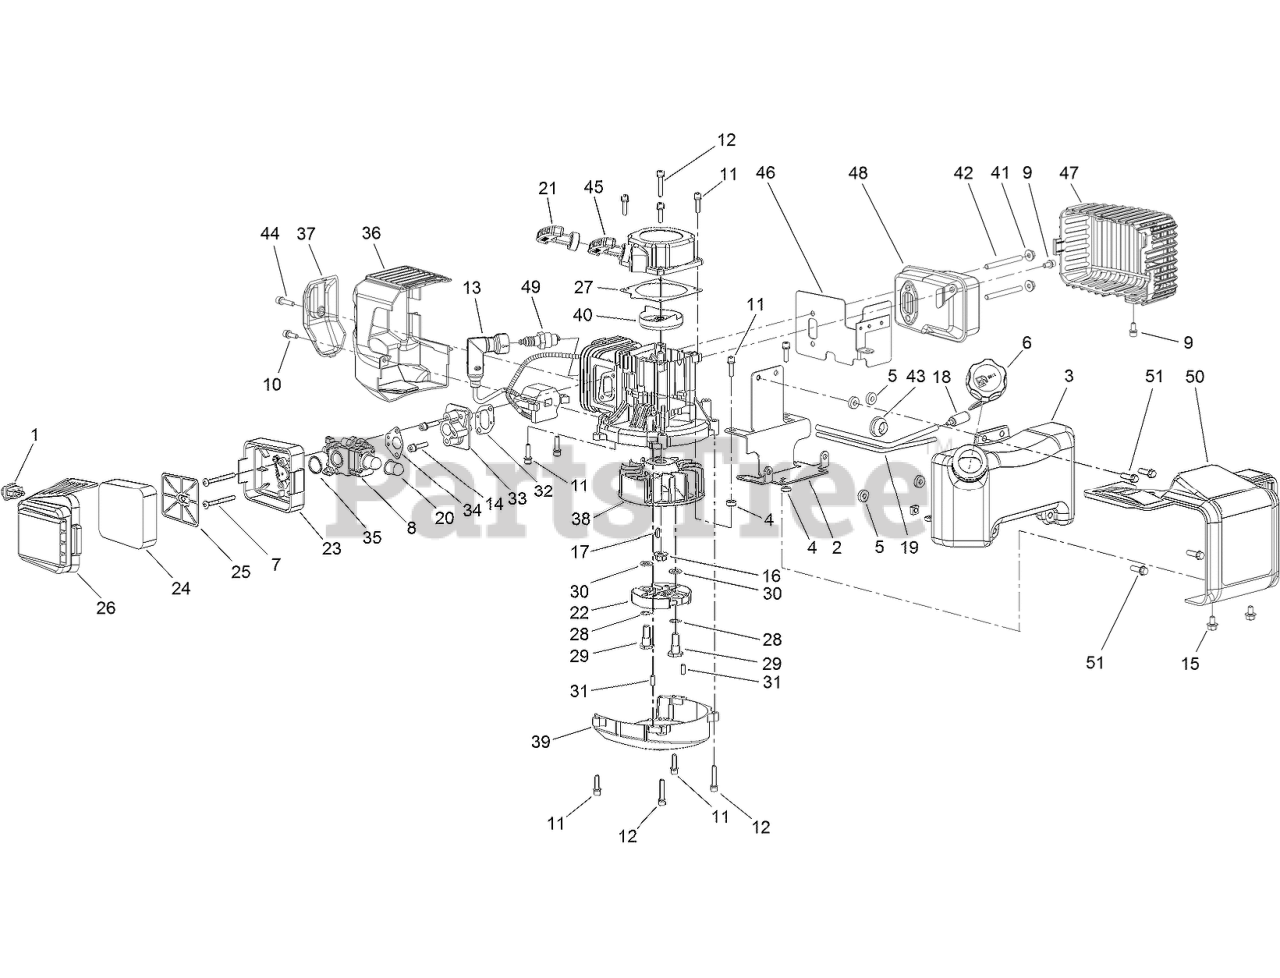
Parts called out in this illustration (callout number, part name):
1	SWITCH
2	MOUNT-TANK, FUEL
3	FUEL TANK AND CAP KIT
4	SPACER
5	SPACER
6	CAP-FUEL
7	SCREW-BSHCS
8	CARBURETOR ASM
9	SCREW-SHCS
10	SCREW-SHCS
11	SCREW-SHCS
12	SCREW-SHCS
13	IGNITION COIL
14	SCREW-SHCS
15	SCREW-HHF
17	KEY-WOODRUFF
18	FUEL FILTER
19	FUEL LINE KIT
20	PRIMER BULB
21	HANDLE-RECOIL
22	CLUTCH SPRING ASM
23	AIR FILTER BASE
24	PREFILTER-FOAM
25	AIR FILTER FRAME
26	COVER-FILTER, AIR
27	SPACER-PLATE, RECOIL
28	WASHER-WAVE
29	SCREW-HH
30	WASHER-PLAIN
31	PIN-DOWEL
32	GASKET-INTAKE
33	MANIFOLD-INTAKE
34	GASKET-CARBURETOR
35	O-RING
36	SHROUD-ENGINE
37	SHROUD-ENGINE
38	FLYWHEEL
39	SHROUD-FLYWHEEL
40	CLUTCH-RECOIL
41	NUT-HEX
43	GROMMET-FUEL TANK
44	SCREW-SHCS
45	RECOIL ASM
46	SHIELD-MUFFLER
47	GAURD-MUFFLER
48	MUFFLER
49	SPARK PLUG
50	SHROUD-TANK, FUEL
51	SCREW-HHF
